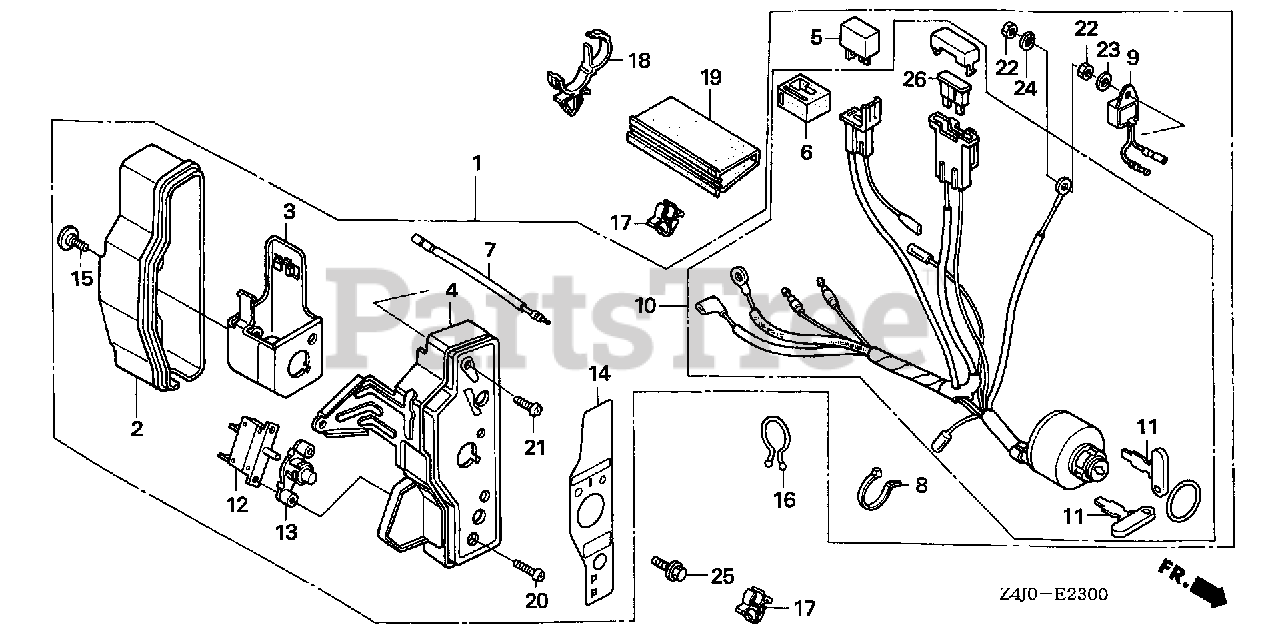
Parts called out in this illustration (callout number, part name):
1	BOX ASSY., CONTROL *R280* (EXP-ALERT) (POWER RED)
1	BOX ASSY., CONTROL *NH1* (EXP-ALERT) (BLACK)
2	CASE, CONTROL
3	BRACKET, CASE MOUNTING
4	PANEL, CONTROL *NH1* (BLACK)
4	PANEL, CONTROL *R280* (POWER RED)
5	RECTIFIER ASSY., SILICON (SHINDENGEN)
6	SUSPENSION, CONNECTOR
7	SUB-WIRE HARNESS
8	BAND
9	ALERT UNIT, OIL
10	SWITCH ASSY., COMBINATION
11	KEY
12	PROTECTOR, CIRCUIT (1.0A)
13	LENS ASSY., PROTECTOR
14	MARK, CONTROL BOX (EXTERNAL)
15	SCREW, SPECIAL (6X12)
16	CLIP, PURSE LOCK
17	CLIP, CORD
18	STRAP, WIRE HARNESS (25MM) (BLACK)
19	TUBE, FASTENER (30)
20	SCREW, PAN (3X12)
21	SCREW, PAN (4X12)
22	NUT, HEX. (4MM)
23	WASHER, PLAIN (4MM)
24	WASHER, SPRING (4MM)
25	BOLT, FLANGE (6X10)
26	FUSE, BLADE (5A)
